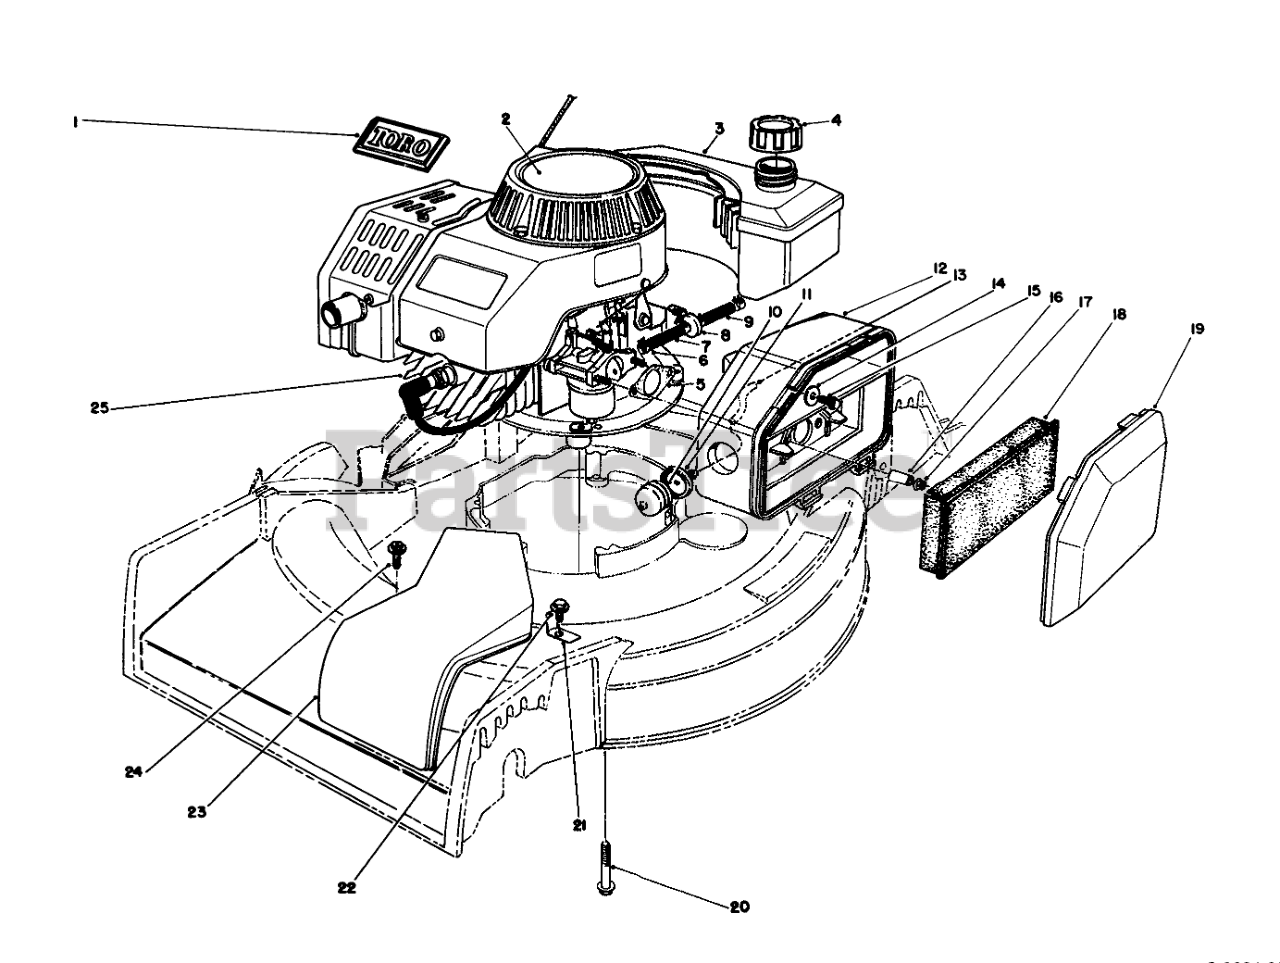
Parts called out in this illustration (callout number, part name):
1	TORO LOGO PLT
2	DECAL- 2 CYC RECOIL
3	FUEL TANK ASM
4	GAS CAP ASM
5	GASKET-AIR CLEANER
6	CLAMP-FUEL LINE
7	HOSE-FUEL
8	FILTER-FUEL
9	HOSE-FUEL
10	BULB-PRIMER
11	BODY-PRIMER
12	BODY-AIR CLEANER
13	HOSE-PRIMER
14	WASHER-FLAT
15	SCREW-HH
16	SPACER
18	ELEMENT-AIR CLEANER
19	COVER-AIR CLEANER
20	SCREW-HHF, WHIZ
21	BELT GUIDE
22	SCREW-HWHTF
23	BELT COVER 21" S D
24	SCREW
25	Engine
